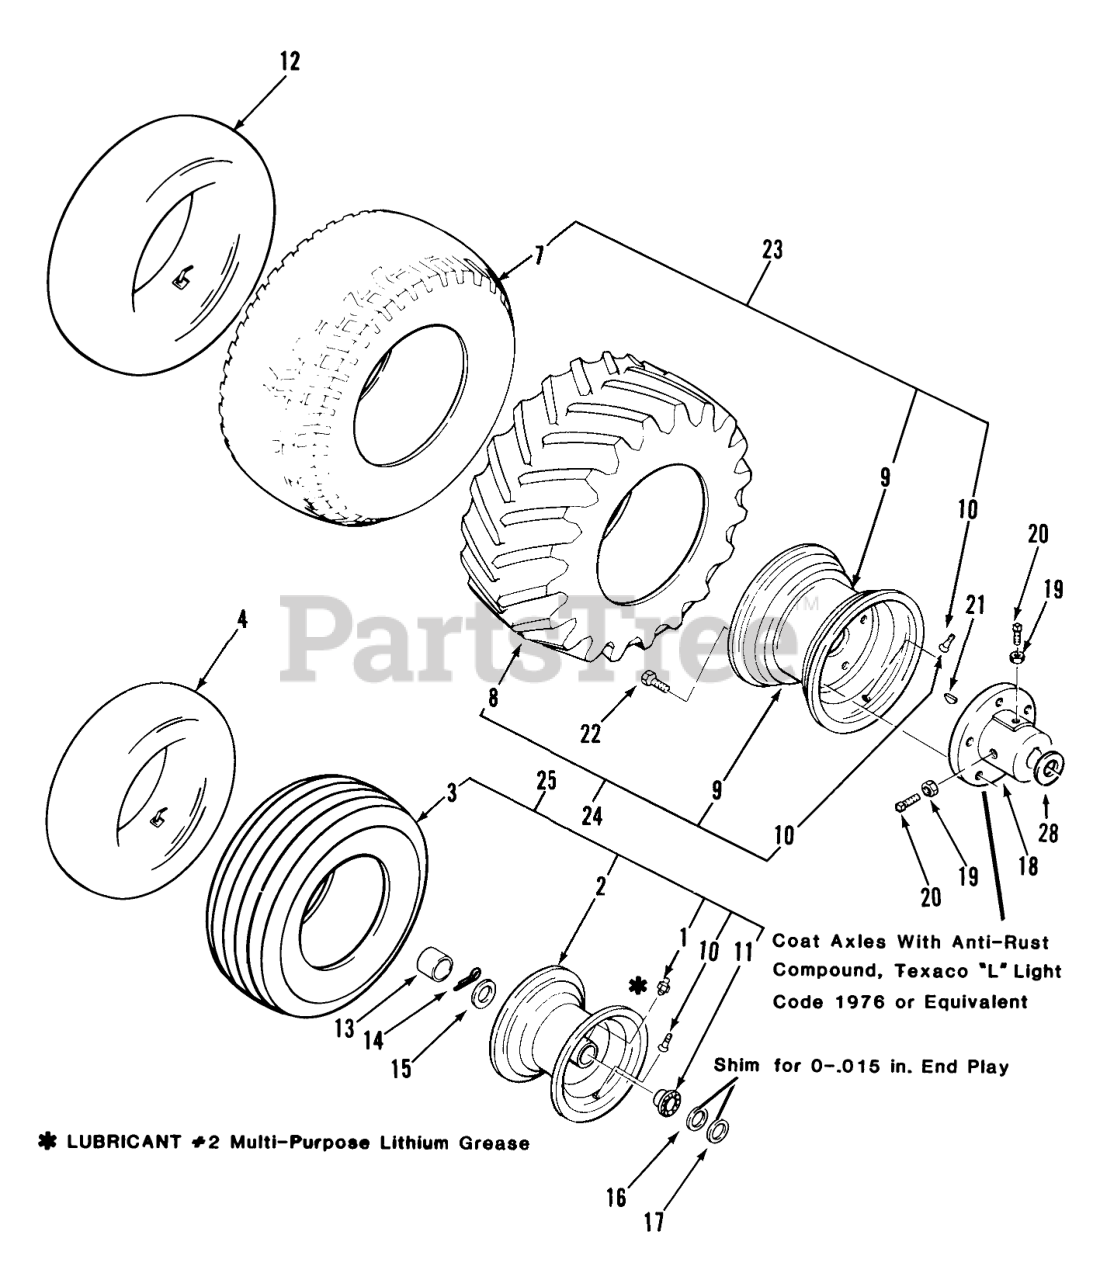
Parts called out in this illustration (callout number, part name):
1	ZERK-GREASE
2	Front Wheel (Includes Item 1, 10, 11) 310
2	Front Wheel (Includes Item 1, 10, 11) 312
2	Front W heel (Includes Item 1, 10, 11) 414, 416
3	TIRE15 X 6.00-6
3	TIRE TURF SAVER 16X6.50-8
4	TUBE-INNER
7	TIRE-22 X 8.00-12
7	TIRE 22 X 9.00-12
7	Tire
7	Engine
8	Tire-Cleat, Rear
9	WHEEL
10	VALVE
11	BEARING-WHEEL
12	INNER TUBE
12	TUBE-INNER
12	Tube Cleat Tires
13	HUB CAP-FLAT BLACK
13	HUBCAP
14	COTTER PIN-4
15	WASHER-WHEEL
15	WASHER WHEEL
16	WASHER
17	WASHER-SHIM
18	Hub Rear
18	Hub-Rear
19	Nut
20	Screw-Set
21	KEY-WOODRUFF
21	WOODRUFF KEY
22	Lug Nut
23	Rear Wheel & Tire Assy 310
23	Rear Wheel & Tire Assy 312
23	Rear Wheel & Tire Assy 414
23	Rear Wheel & Tire Assy 416
24	ASSY WHEEL & TIRE
25	Front Wheel & Tire Assy 310
25	Assy-Wheel & Tire Front
25	Front Wheel & Tire Assy 414, 416
